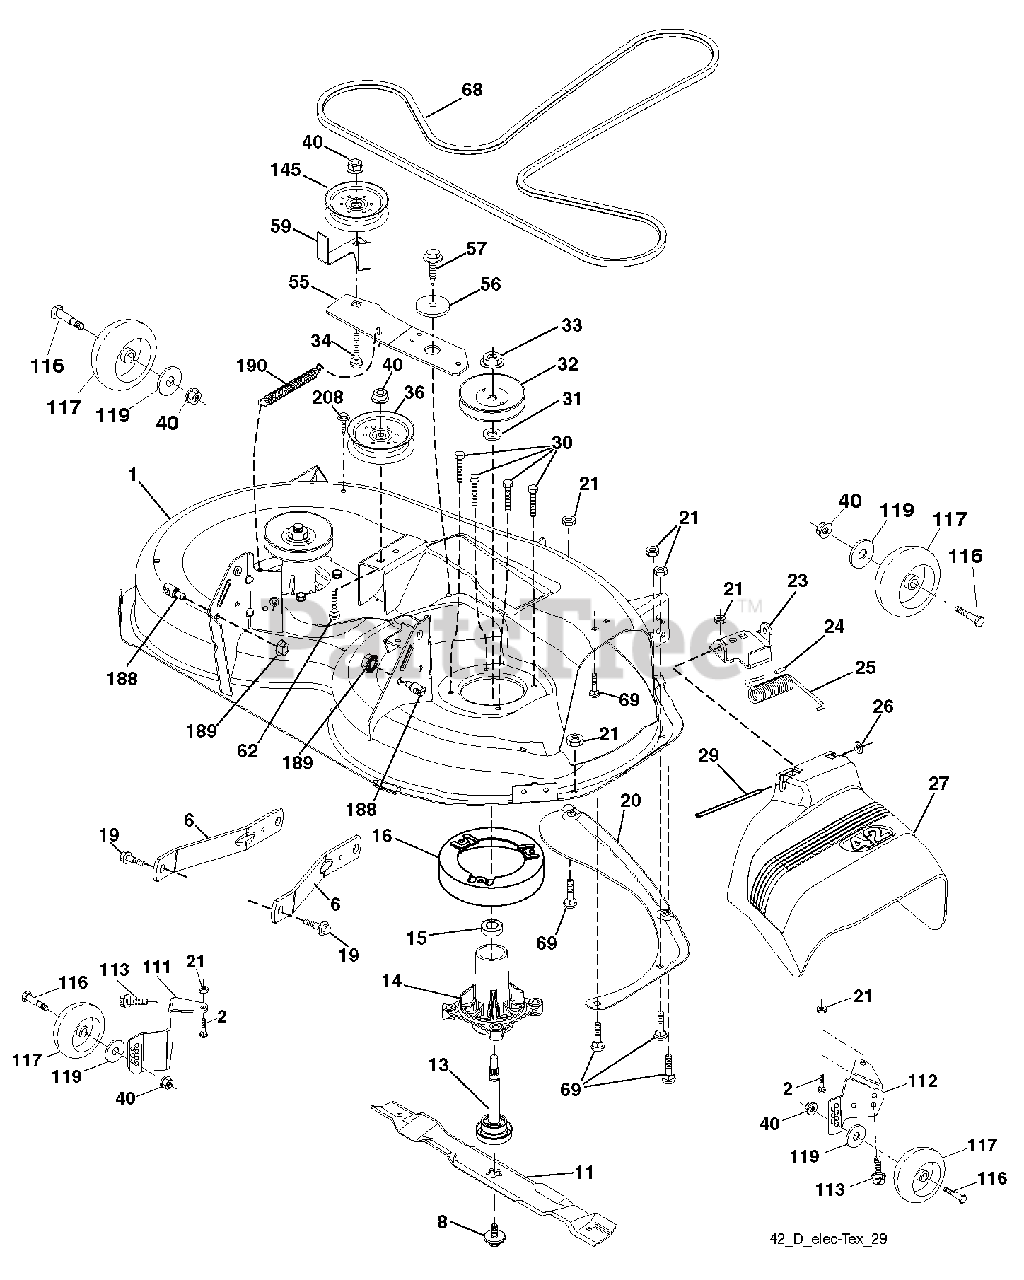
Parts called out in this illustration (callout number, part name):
1	DECK.WELDMENT.42"
2	BOLT
6	ARM.SUSPENSION.MOWER.R
8	BOLT.WASHER.ASM.7/16-2
11	42" HI-LIFT BLADE
13	SHAFT.ASM.MDRL.N/GREASE.38
14	HOUSING MANDREL
16	STRIPPER, MWR ROUND
19	BOLT.SHOULDER
20	BAFFLE.VORTEX
21	LOCKNUT
23	BRKT.DEFLECTOR.38"2005+
24	CAP-SLEEVE LT
25	SPRING.TORSION.DEFLECT
26	NUT PUSH M
27	SHIELD.DEFLECTOR.MOWER.42"BLAC
29	ROD.HINGE
30	SCREW, WASHER HEAD
31	WASHER.SPACER.MANDREL
32	PULLEY/MANDREL
33	NUT.FLANGE.LOCK.TOP
34	BOLT.3/8-16X1.50
36	PULLEY.IDLER.2006
40	NUT LOCK FLG 3/8-16 UNC
55	IDLER.ARM.42"
56	SPACER.RETAINER
57	SCREW 3/8-16X1
59	GUARD, BELT
62	BOLT
68	BELT V SECONDARY
69	BOLT
111	BRKT.WHEEL.GAUGE.LH.42"
112	BRKT.WHEEL.GAUGE.RH.42"
113	BOLT.5/16HEX.WHS.HD
117	WHEEL.GAGE.HALF.SPOKED
119	WASHER
145	PULLEY.IDLER.48"PRIMARY
188	STUD.FASTNER.W/ANTI-ROTATE
189	NUT LOCK HEX FLANGE 5/16-18
190	SPRING.MOWER.DRIVE.ELECTRIC
208	SCREW 3/8-16X1/2
